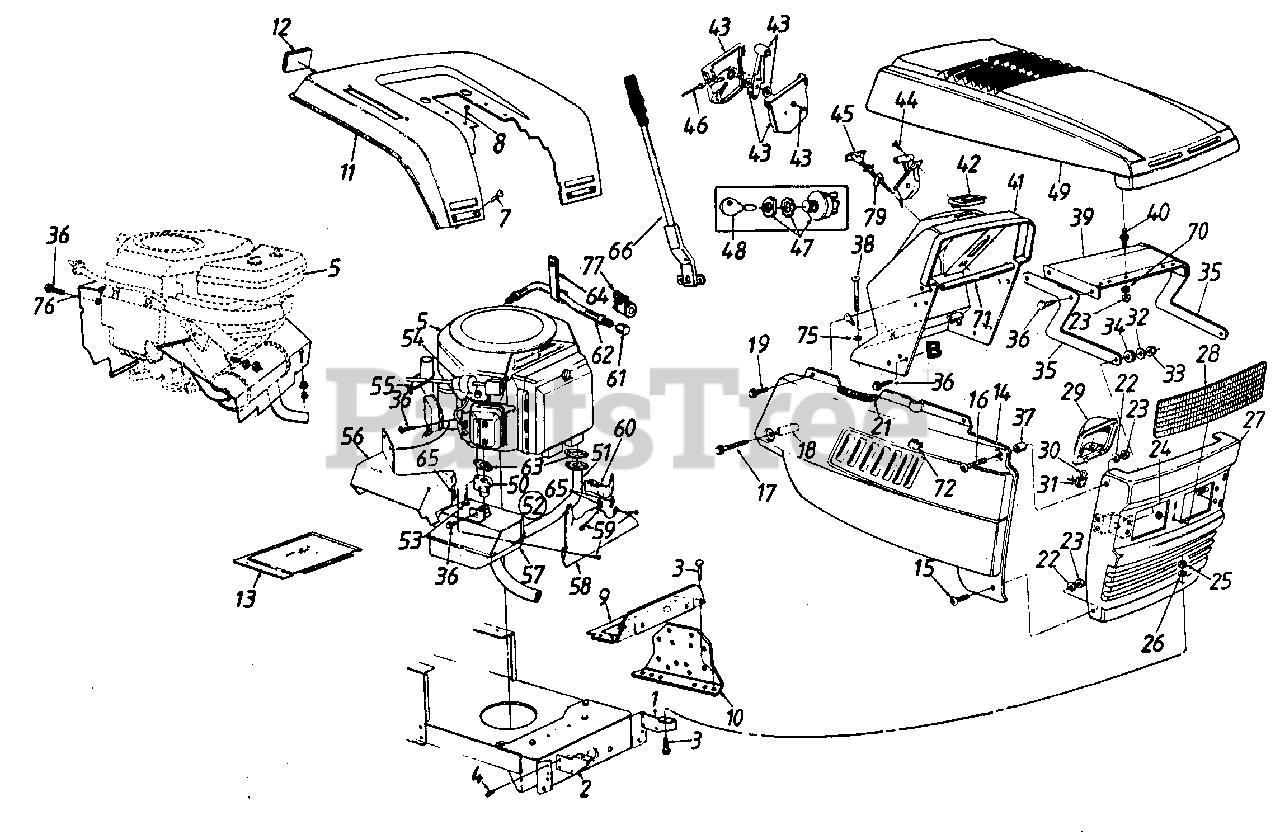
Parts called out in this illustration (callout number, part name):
1	Grille Mtg. Brkt.-L.H.
4	Hex Wash. Hd. Tap Scr. 5/16-18 x .5" Lg.
5	Engine
7	Carriage Bolt 1/4-20 x .5" Lg.
8	Hex Wash. Hd. Tap Scr. 5/16 x .75" Lg.
9	Support Bracket
13	Transmission Cover
14	Side Panel-R.H.
15	Truss Mach. Scr. 1/4-20 x .5" Lg.
16	Truss Mach. Scr. 1/4-20 x 1.0" Lg.
17	Hex Wash. TT-Tap Scr. 1/4-20 x 1.75" Lg.
18	Spacer .26" I.D. x 1.32"
19	Hex Rolling Tap Scr. 1/4-20 x .75" Lg.
21	Trim Strip-12" Lg.
22	L-Wash. 1/4" I.D.
23	Hex Nut 1/4-20 Thd.
24	Speed Nut 5/16" Thd.
25	Hex Nut 5/16-18 Thd.
26	L-Wash. 5/16" I.D.
29	Headlamp Housing
30	Headlamp
31	Twist Lock Lamp Socket
32	Bell-Wash. .345" I.D. x .88"
33	Hex L-Nut 5/16-18 Thd.
34	Rubber Washer
35	Hood Hinge
36	Hex Wash. Hd. B-Tap Scr. 1/4-20 x .5" Lg.
37	Spacer .262" I.D. x .31"
38	Carriage Bolt 1/4-20 x 1.25" Lg.
39	Hood Plate
40	Double Ended Stud 1/4-20 Thd.
41	Dash
42	Ammeter
43	Throttle Control Box Ass'y.
44	Mach. Scr. #10 x .44" Lg.
45	Choke Control
46	Throttle Control Wire
47	Ignition Switch
48	Ignition Key
50	Inlet Tube Ass'y.
51	Formed Tube Ass'y.
52	Muffler Ass'y. Comp.
53	Hex Bolt w/Washer
54	Hose Clamp .406" Dia.
55	Cable Tie
56	Muffler Heat Shield
57	Exhaust Muffler Sub Ass y.
58	Front Heat Shield
59	Hex AB-Tap Scr. #10 x .5" Lg.
60	Front Heat Shield Ext.
61	Cap Oil Drain
62	Oil Drain
63	Exhaust Gasket
64	Clamp
65	Speed Nut #10-24 Thd.
66	Lift Handle
70	Bell-Wash. .265" I.D. x .75"
71	Grille Support Tube
72	Mounting Clamp
75	Retaining Nut
76	Baffle w/Trim Strip
77	Clamp
79	Choke Retainer
